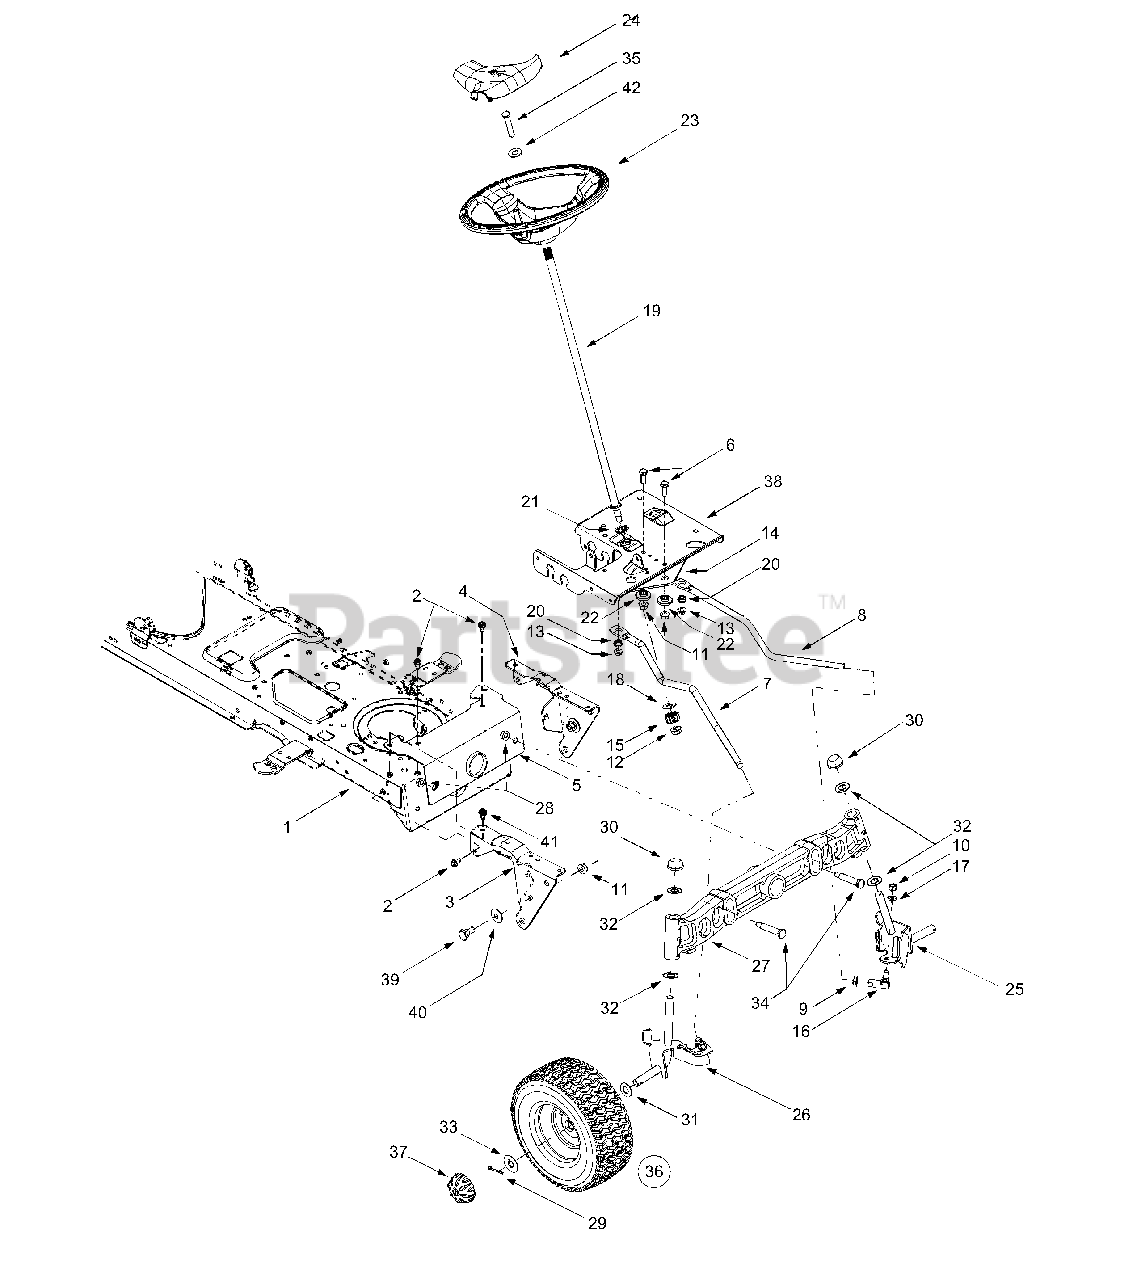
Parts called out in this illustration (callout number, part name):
6	Hex Cap Screw, 3/8-16 x 1 (Grade 5)
7	RH Drag Link
9	Jam Nut, 7/16-20 (Grade 2)
10	Hex Nut, 3/8-24 (Grade 2)
11	Flange Lock Nut, 3/8-16
12	Flange Lock Nut, 7/16-20
13	Flange Lock Nut, 5/16-18
14	Steering Gear, 11/90 Ratio
15	Steering Pinion Gear
16	Ball Joint, 7/16-20
17	Lock Washer, 3/8
18	Flat Washer, .51 x 1.12 x .06
19	Steering Shaft, .625 OD x 24.4
20	Plastic Bushing, .38 ID
21	Hex Flange Bearing, 5/8
22	Shoulder Spacer, .38 ID
23	Soft Touch Steering Wheel
24	Steering Wheel Cap
25	LH Axle Assembly, .625 Dia. (Model LT-1650)
25	LH Axle Assembly, .625/.750 Dia. (Models LT-1850/2150)
26	RH Axle Assembly, .625 Dia. (Model LT-1650)
26	RH Axle Assembly, .625/.750 Dia. (Models LT-1850/2150)
27	Cast Iron Pivot Bar w/ Fittings, .625 (Model LT-1650)
27	Cast Iron Pivot Bar w/ Fittings, .750 (Models LT-1850/2150)
28	Flange Lock Nut, 3/8-16
30	Push Cap, .625
31	Flat Washer, .64 x 1.0 x .12
32	Flat Washer, .64 x 1.24 x .06 (Model LT-1650)
32	Flat Washer, .78 x 1.59 x .06 Models LT-1850/2150)
33	Flat Washer, .635 x 1.589 x .06
34	Shoulder Screw, .5 x 2.2, 3/8-16
35	Hex Bolt, 5/16-18 X 1
37	Hub Cap
39	Shoulder Screw, 3/8-16
40	Bell Washer, .39 x 1.13 x .062
41	Self-tapping Screw, 5/16-18 x .75
42	Bell Washer, .34 x .872
